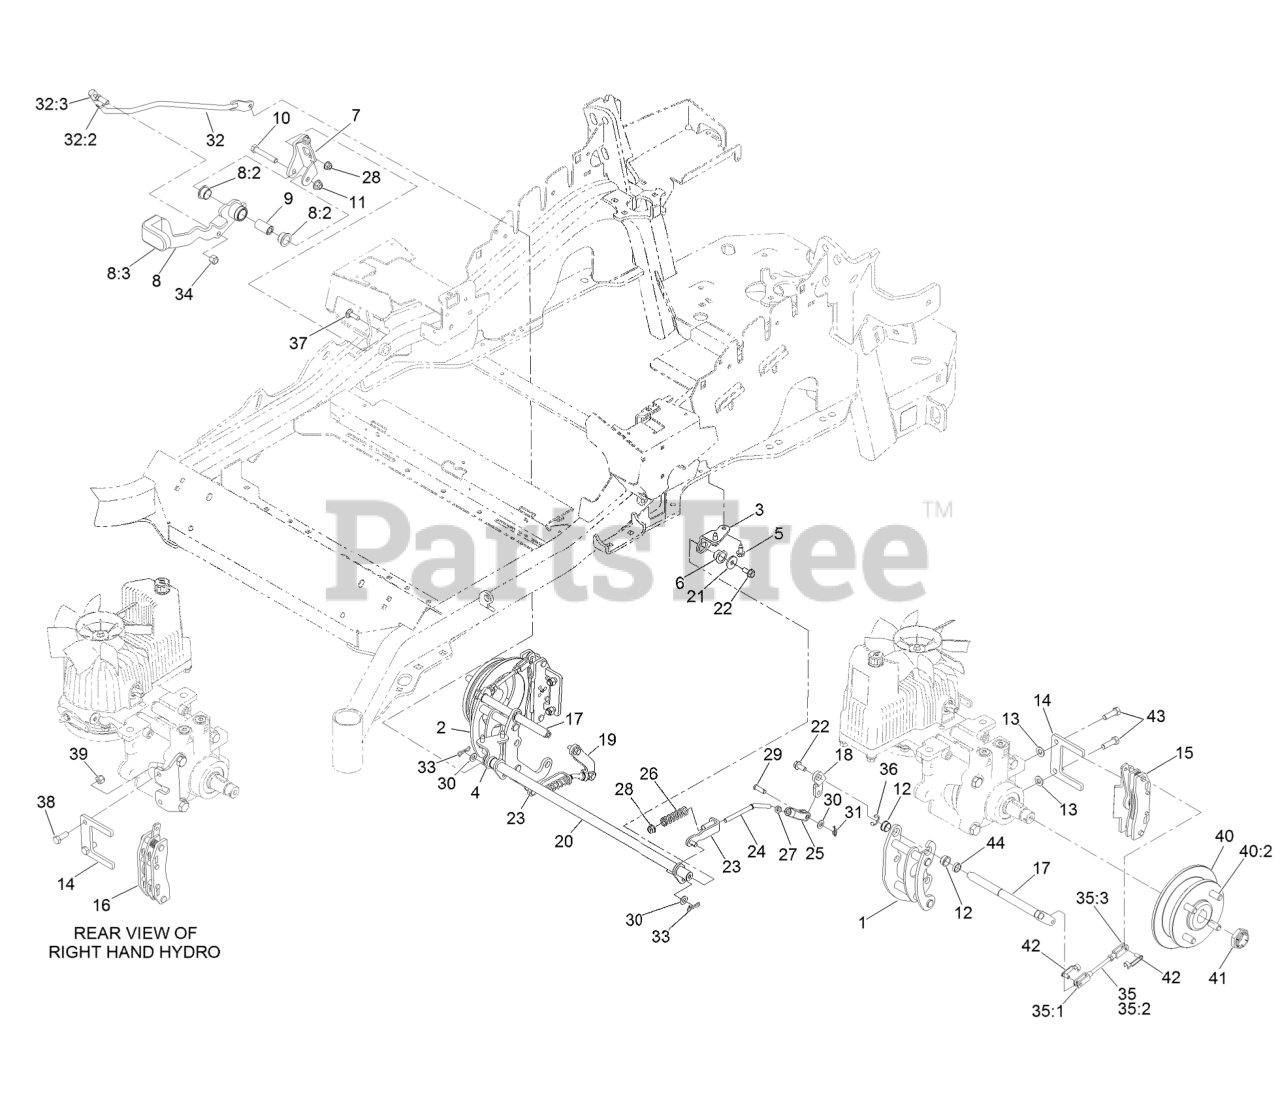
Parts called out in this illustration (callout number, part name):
1	BRACKET-MOUNT
2	BRAKE LEVER ASM W/ GRIP
2:2	BUSHING-FLANGE
2:3	GRIP-LEVER
3	BOLT-CARR
4	NUT-HF, NI
5	HANDLE-PIVOT, BRAKE
6	SCREW-HH
7	NUT-HF, NI
8	WHEEL HUB ASM
8:2	STUD-WHEEL
9	Wheel And Tire ASM
9:3	Stem-Valve
10	CALIPER-BRAKE
11	CALIPER-BRAKE, RH
12	NUT-LUG
13	PLATE-MOUNT, BRAKE
14	SCREW-LOCK, PATCH
15	MOUNT-BELLCRANK, LH
16	MOUNT-BELLCRANK, RH
17	DECAL-TORQUE, WHEEL HUB LUG
18	BELLCRANK
19	BUSHING
20	ARM-INNER, LH
21	ARM-INNER, RH
22	LOCKNUT
23	WASHER-FLAT
24	MOUNT-PIVOT, LH
25	MOUNT-PIVOT, RH
26	Screw-HWH 5/16-18 X 3/4 Tf
27	BUSHING-FLANGE
28	SHAFT-CROSS
29	WASHER-FLAT
30	SCREW-HHF
31	BRACKET-L
32	LINKAGE-MID
33	YOKE-OFFSET
34	SPRING-COMPRESSION
35	NUT-JAM
36	PIN-CLEVIS
37	WASHER-PLAIN
38	PIN-COTTER, LOCKING
39	FRONT LINKAGE ASM
39:2	END-TIE ROD, RH
39:3	NUT-HJ
40	PIN-COTTER, LOCKING
41	NUT-LOCK
42	REAR LINKAGE ASM
42:3	NUT-JAM
44	SCREW-HH
45	NUT-LOCK, NI
47	PIN-CLEVIS, SPRING
